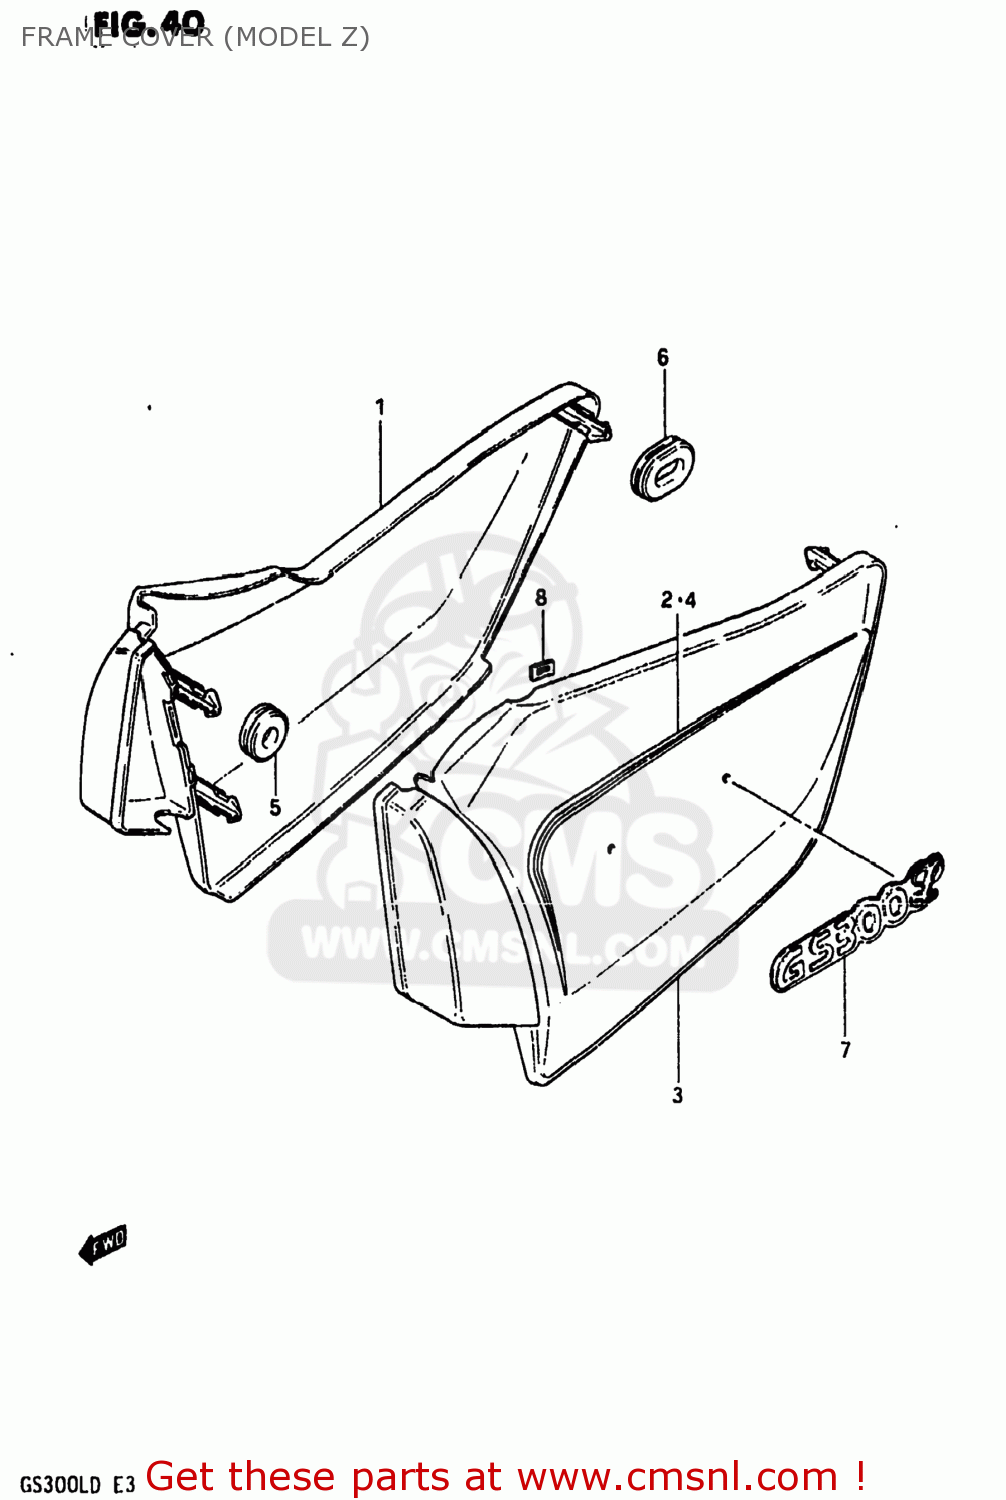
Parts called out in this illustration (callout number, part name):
1	COVER,FRAME,RIGHT
2	TAPE SET,FRAME COVER,RIGHT
3	COVER,FRAME,LEFT
4	TAPE SET,FRAME COVER
5	CUSHION
6	CUSHION
7	EMBLEM,FRAME COVER
8	NUT
